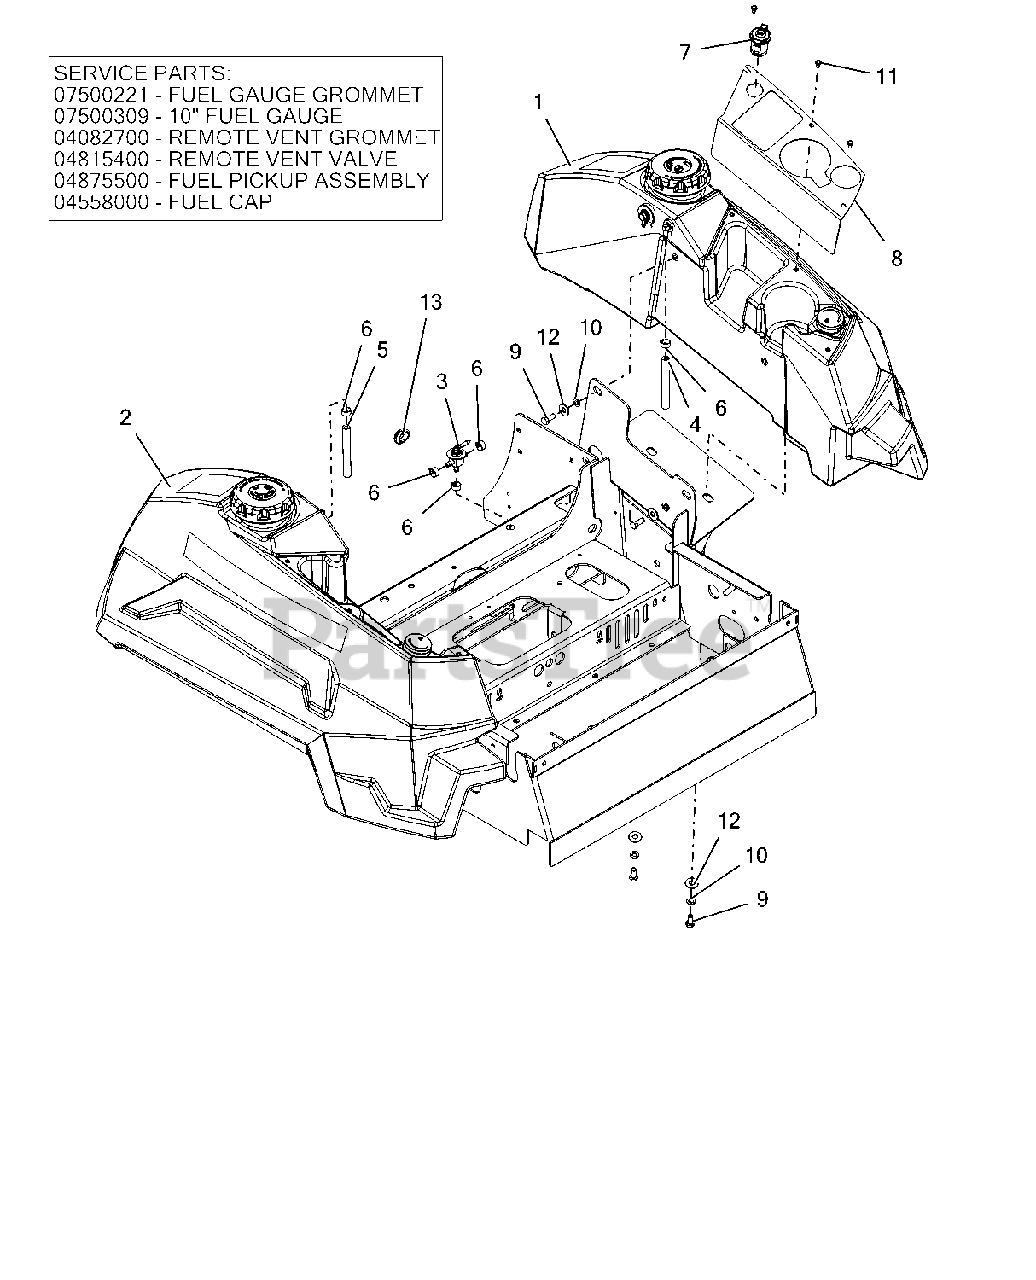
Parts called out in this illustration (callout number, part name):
1	ASSY-LH, PT400 FUEL TANK
2	ASSY-RH, PT400 FUEL TANK
3	VALVE, FUEL
4	.25 LOW-PERM GAS HOSE 19.00" LG - LH TANK TO VALVE
5	.25 LOW-PERM GAS HOSE 32.00" LG - LH TANK TO VALVE
6	CLAMP, FUEL LINE
7	PORT, 12 VOLT POWER
8	PLATE, CUP HOLDER
9	BLT-HEX .31-18X.75 GR5 YWZC
10	WSHR-LK .31X.078 REG YWZC
11	SCR-MCH 10-24X.38 HWHSTAINLESS
12	WSHR-FL-STL.38X.875X.083 YWZC
13	GROMMET, RUBBER
14	FUEL GAUGE GROMMET
15	10" FUEL GAUGE
16	REMOTE VENT GROMMET
17	REMOTE VENT VALVE
18	FUEL PICK-UP ASSEMBLY
19	FUEL CAP
